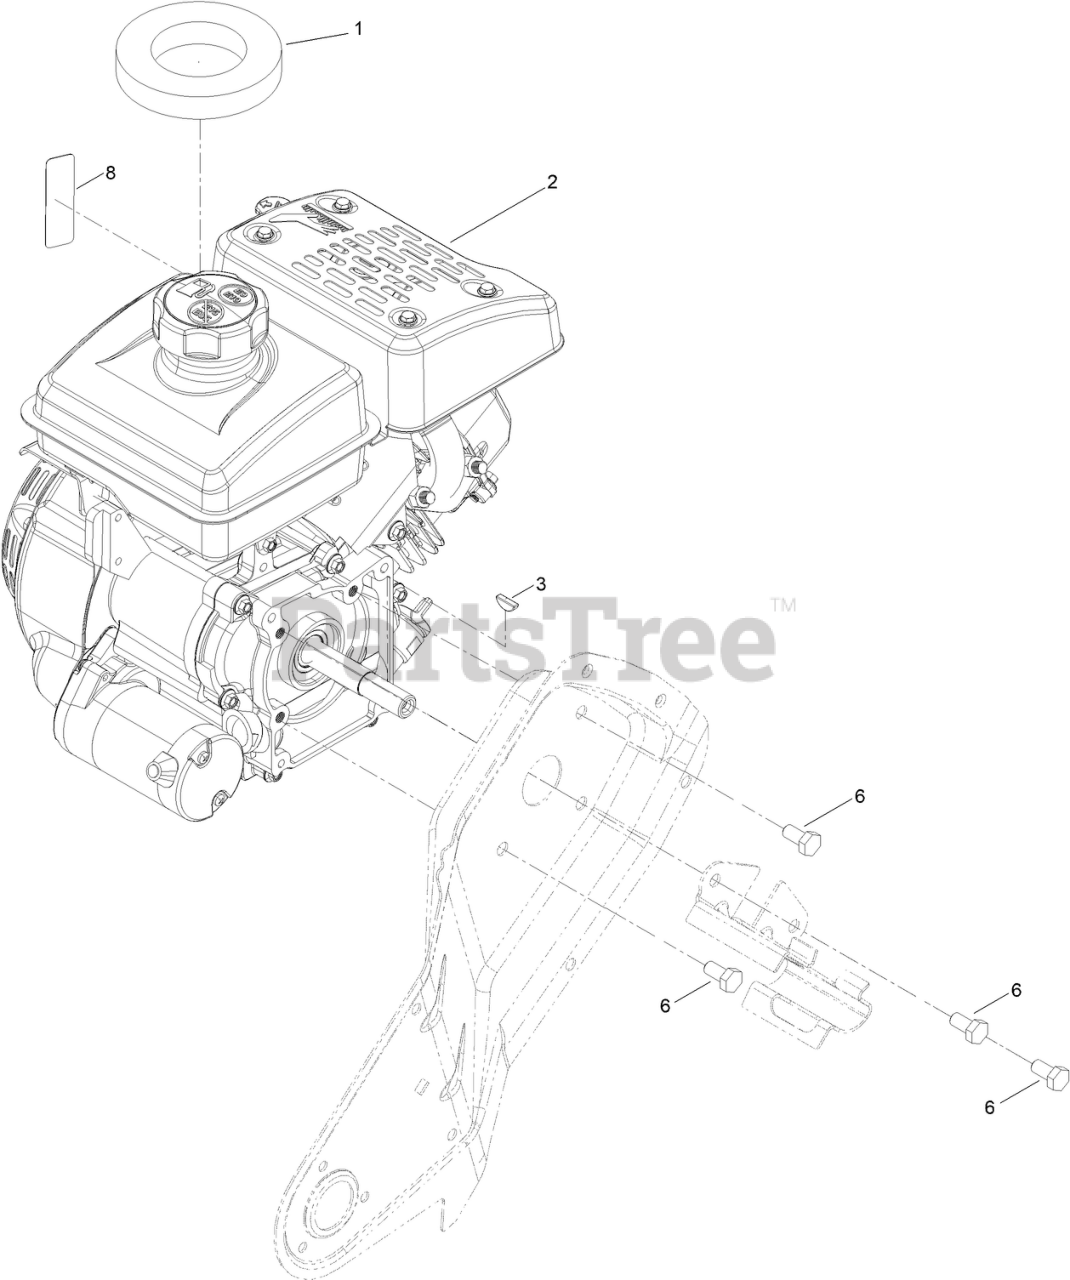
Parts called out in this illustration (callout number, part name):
1	SEAL-TANK
2	ENGINE-LC156FS
3	KEY-WOODRUFF
6	BOLT
8	DECAL-CONTROLS, ENGINE
